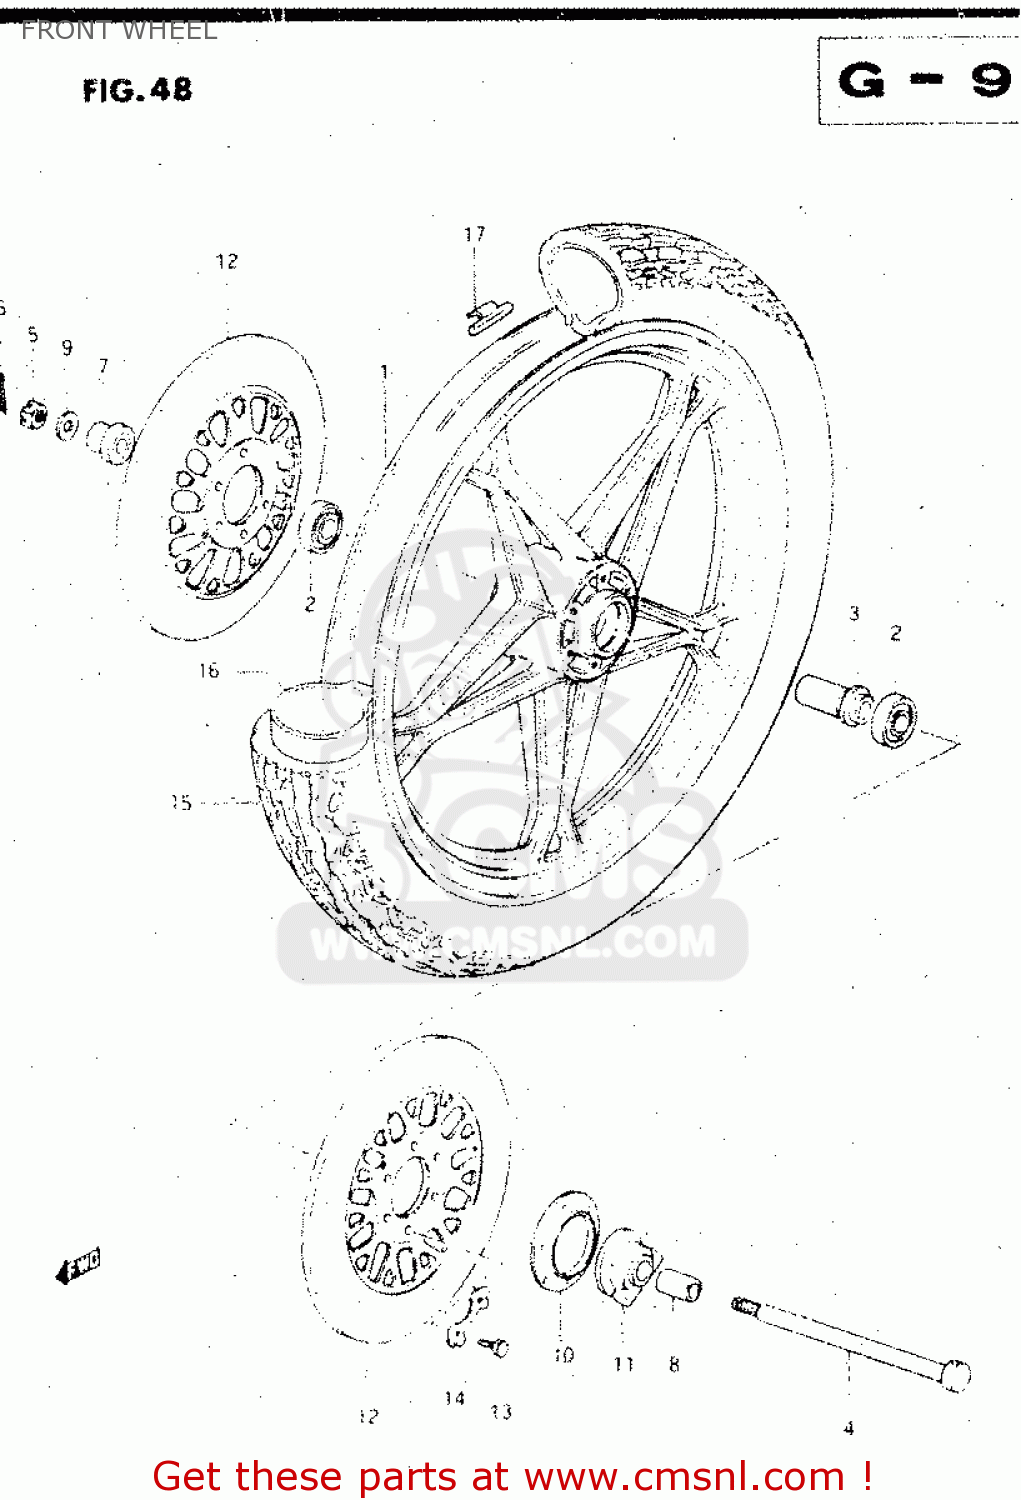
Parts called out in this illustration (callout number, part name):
1	WHEEL, FRONT (19X1.85) (GRAY)
2	BEARING
3	SPACER,FR HUB BEARING
4	AXLE,FRONT
5	NUT 12MM
6	COTTER PIN
7	SPACER,FR HUB BEARING,R
8	SPACER(15X22X30)
9	WASHER
10	DUST SEAL,SPEEDOMETER GEAR BOX
11	BOX ASSEMBLY,SPEEDOMETER GEAR
12	DISC,FR BRAKE
13	BOLT(8X25)
14	WASHER
15	TIRE,FRONT
16	TUBE,INNER
17	BALANCER,WHEEL
